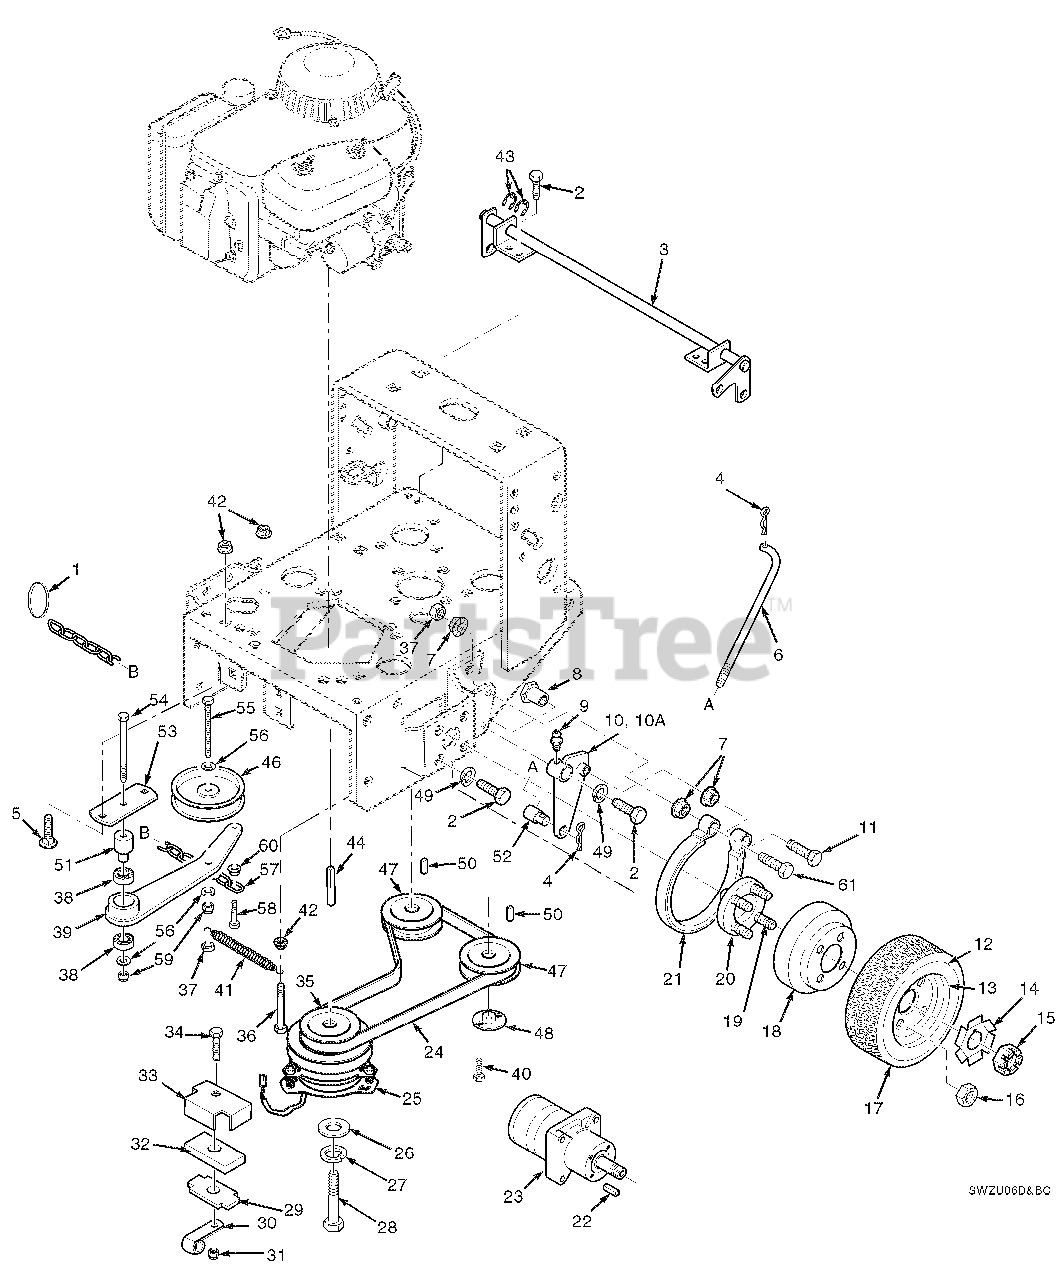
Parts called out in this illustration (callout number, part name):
1	Ring, Split
2	Bolt, 3/8-16 x 1" Hex Head
3	Brake Shaft Assembly Weldment
4	Hair Pin Cotter, .094 x 1.62
5	Carrage Bolt, 5/16-18 x .75"
6	Rod, Brake Lower
7	Nut, 3/8-16 Serr. Flange
8	Bushing, Brake
9	Grease Fitting
10	Brake Actuator Wlmt., LH
10A	Brake Actuator Wlmt., RH
11	Bolt, 3/8-16 x 2-1/4"
12	Tire, 18 x 8.50, 4 ply
13	Rim Assy
14	Lock Washer, Wheel Motor
15	Hex Castle Nut, 3/4-28 UNEF
16	Nut, Lug
17	Wheel Assy.
18	Brake Drum
19	1/2-20 Serrated Bolt
20	Hub, Wheel
21	Brake Band, 7-1/2"
22	Key, 3/16 X 3/4" Woodruff
23	Wheel Motor
24	Belt, Pump Drive
25	Electric Clutch
26	Flat Washer .469" x 1.75" x .25"
27	Lock Washer, 7/16"
28	Hex Head Bolt, 7/16-20 x 2-3/4"
29	Plate, Backing
31	Nut, 5/16-18 Elastic Stop
32	Rubber Pad, Clutch Stop
33	Retainer, Clutch Stop
34	Hex Head Bolt, 5/16-18 x 1-3/4"
35	Pulley, Pump Drive Engine
36	Hex Head Bolt, 5/16-18 x 2-3/4"
37	Nut, 3/8-16 Center Lock
38	Ball Bearings
39	Idler Arm Weldment, Pump
40	Bolt, Hex Head 1/4-20 x 1" Grd 8
41	Spring, Pump Belt Idler
42	Nut, 5/16-18 Serr. Flange
43	Retaining Ring, 3/4" Ext. "E"
44	Key, 1/4x1/4 x 3-3/4"
45	Flat Washer, 3/8"
46	Pulley, Idler 4-1/2"
47	Pulley, Pump Shaft
48	Tapered Hub
49	Lockwasher, 3/8"
50	Key, 5.0 x 5.0 x 25mm
51	Pivot, Idler
52	Swivel Joint
53	Base, Idler Pivot
54	Bolt, Hex Head 3/8-16 x 3"
55	Bolt, Hex Head 3/8-16 x 2-3/4"
56	Flatwasher 3/8"
57	Chain
58	Bolt, Hex Head 1/4-20 x 1-1/4"
59	Nut, Hex Elastic Stop 3/8-16
60	Nut, Serrated Flange 1/4-20
61	Bolt, Hex Head 3/8-16 x 2.63"
